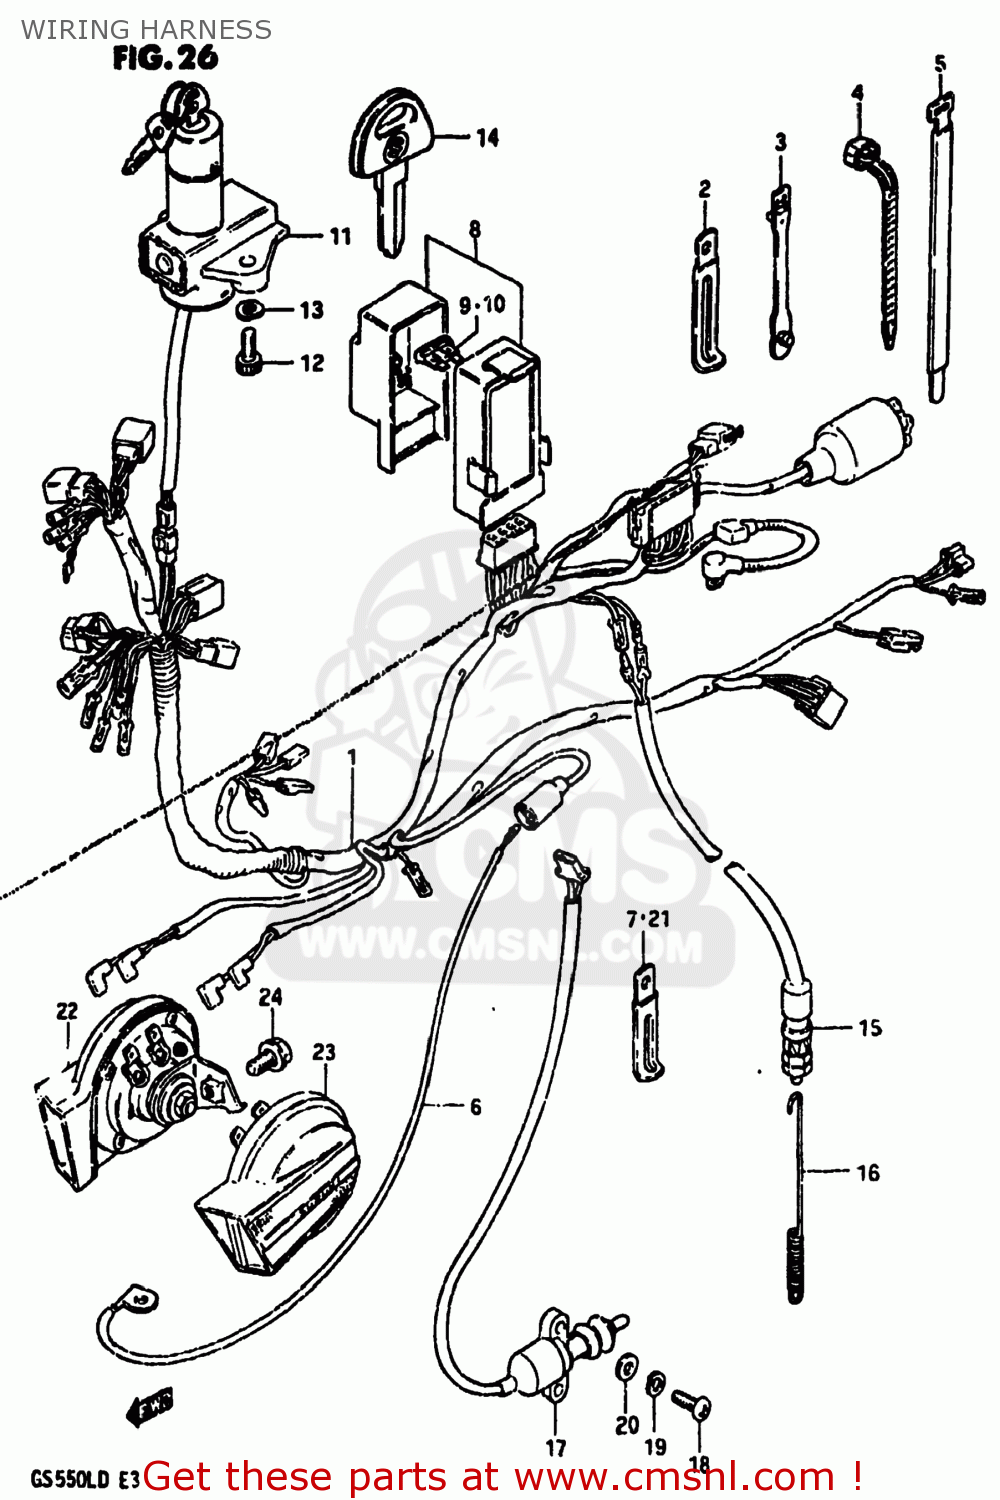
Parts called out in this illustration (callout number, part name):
1	HARNESS,WIRING
2	CLAMP
3	CLAMP,L:88
4	CLAMP(L:125)
5	CLAMP
6	WIRE,OIL PRESSURE SWITCH
7	CLAMP L:35
8	FUSE BOX ASSY
9	FUSE(10A)
10	FUSE(15A)
11	SWITCH ASSY,IGNITION
12	BOLT
13	LOCK WASHER
14	KEY,BLANK
15	SWITCH ASSEMBLY,STOP LAMP
16	SPRING
17	SWITCH ASSEMBLY,SIDE STAND
18	SCREW
19	LOCK WASHER
20	WASHER
21	CLAMP L:35
22	HORN ASSEMBLY,HIGH PITCH
23	HORN ASSEMBLY,LOW PITCH
24	BOLT
